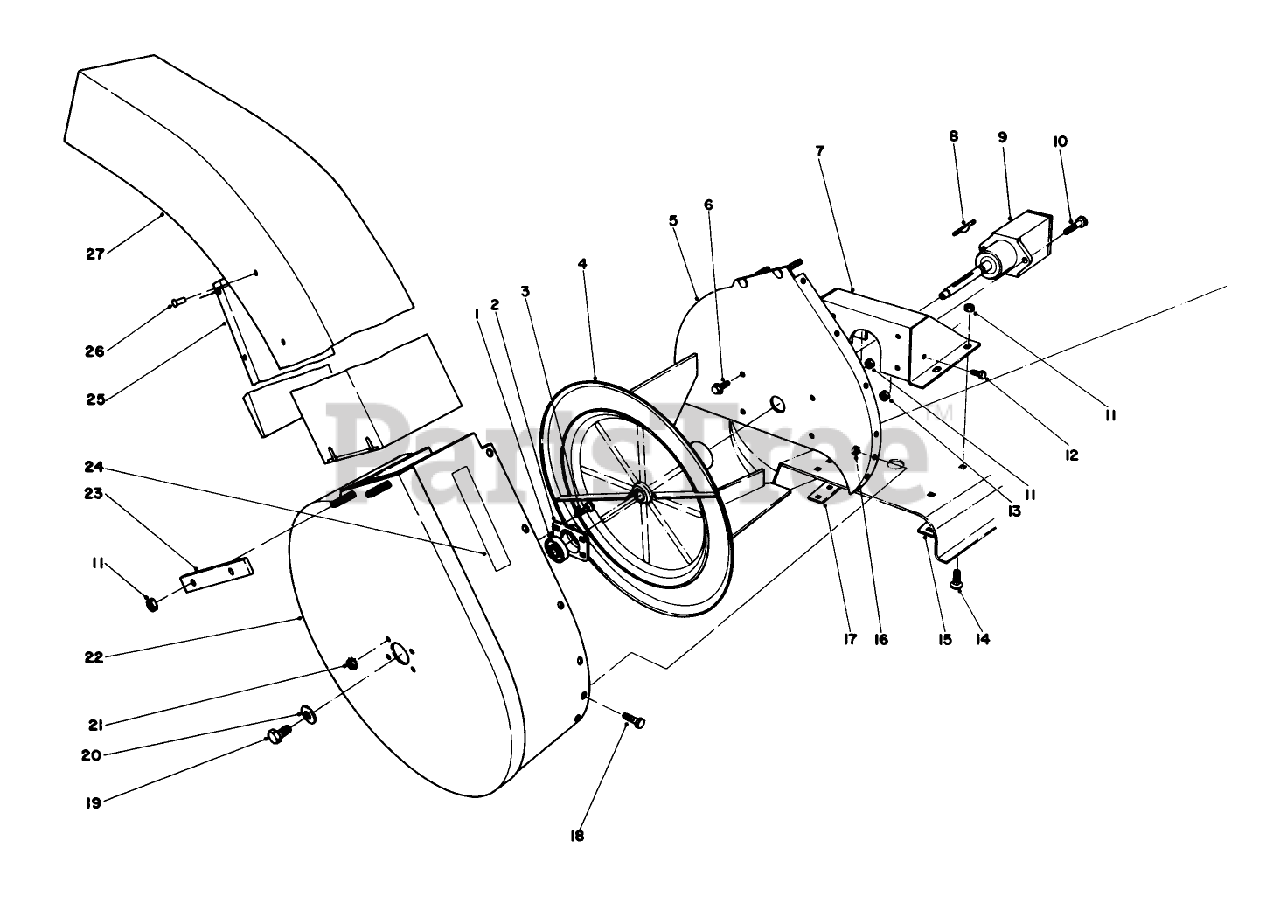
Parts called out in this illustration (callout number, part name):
1	BEARING-BALL
2	BEARING CUP
3	SCREW-CARR
4	Impeller
5	MTG PLATE WA B
6	SCREW-HHF
7	GEAR BOX BRKT WA B
9	GEAR BOX ASM
10	SCREW-HH
11	NUT-LOCK, CONE
12	SCREW-HH
13	NUT-LOCK, CONE
14	BOLT-CARR
15	Plate-Bracket R.H.
17	Plate-Bracket
18	SCREW-HH
19	CAPSCREW 3/8 16 3/4
20	SPACER
21	NUT-KEPS
22	Housing-Blower (Incl. Ref. #24)
23	Bracket
24	Decal-Waming
25	Deflector-Chute
26	Rivet
27	Chute Assembly (Incl. Ref. #25 & 26)
